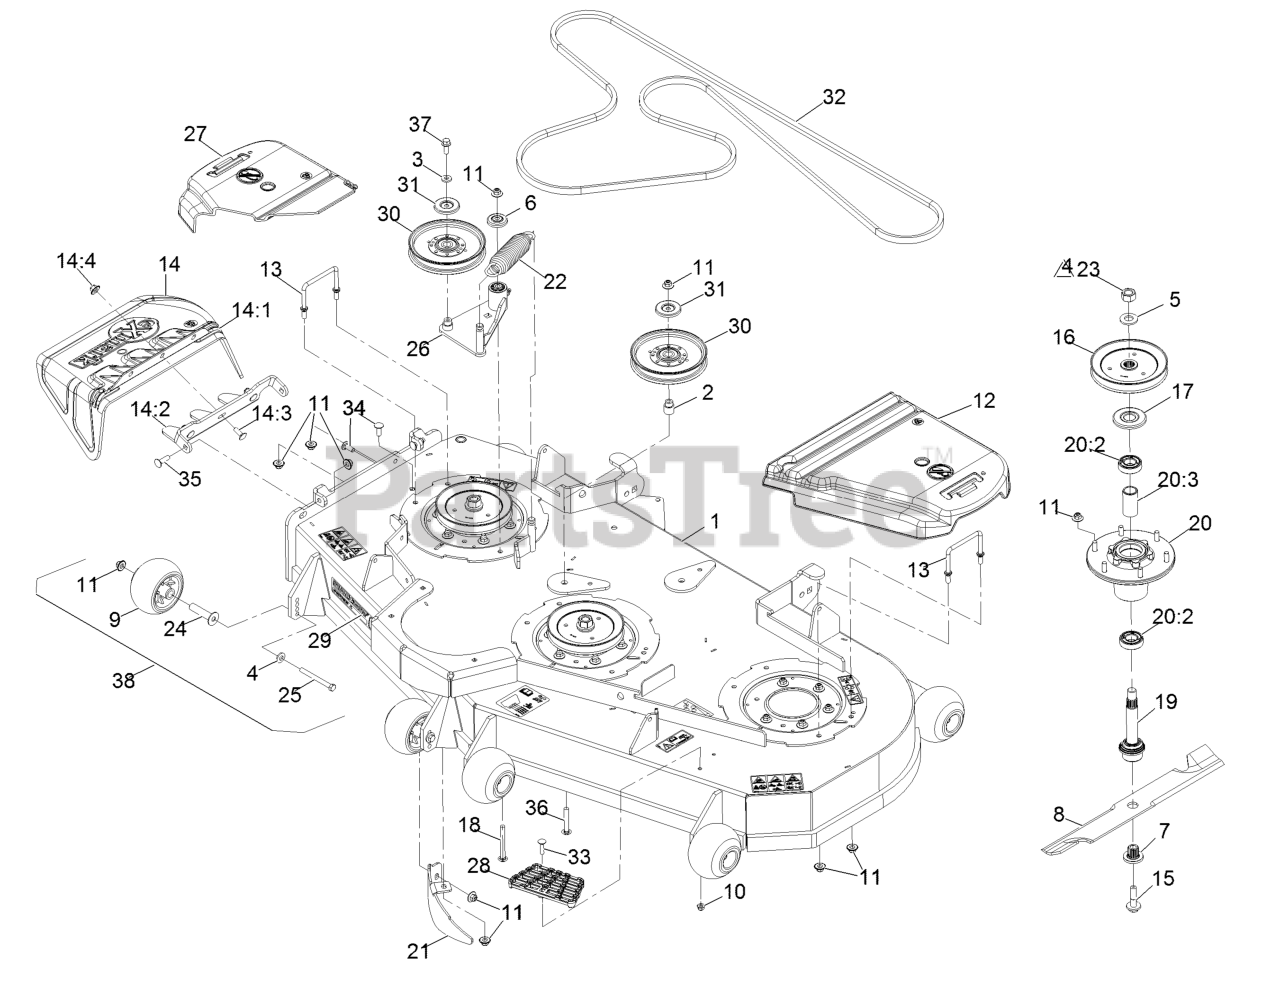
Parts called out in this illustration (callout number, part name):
1	Deck ASM, W/Decals 60
2	Bushing, Idler
4	Washer-Spring Disc 3/8
5	Washer-Spring Disc 3/4
6	Guard-Top
7	Bushing, Splined
8	Blade-Extreme 2, 20.50"
8	Blade, Notched
8	Blade, Mulching
8	Blade, Low Lift
8	Blade, Solid
9	Roller-Anti-Scalp
10	Nut-Nyloc 5/16-18 Flg
11	Nut-Nyloc 3/8-16 Flg
12	Cover-Belt, LH
13	Wireform-Cover
14	ASM,Discharge Chute
14:1	Chute, Discharge
14:2	Bracket,Discharge Chute
14:3	Bolt-Carriage 3/8-16 X 1
14:4	Nut-Nyloc 3/8-16 Flg
15	Screw-Sems 1/2-20 X 2.19
16	Sheave,Blade Drive 6.50
17	Guard,Bearing Top .989
18	Bolt-Carriage Shoulder 3/8-16 X 3 1/2
19	ASM-Spindle And Seal
20	ASM-Cutter Hsg With Bearings
20:2	Bearing-Ball
20:3	Spacer-Bearing
21	Dogleg - Lz60
22	Spring-Extension
23	Nut-Hex
24	Axle, Roller
25	Screw-HH 3/8-16 X 3 3/4 GR 8
26	Idler Arm ASM
27	Beltshield-Rt, 60
28	Step-Deck
29	Decal, 604
30	Idler-Pulley
31	Shield-Dust
33	Bolt-Carriage 5/16-18 X 1 1/4
34	Bolt-Carriage 3/8-16 X 1
35	Bolt-Carriage 3/8-16 X 1 1/4
36	Bolt-Carriage 3/8-16 X 2 1/2
37	Screw-HH Flg 3/8-16 X 1
38	Kit, Anti-Scalp Roller
